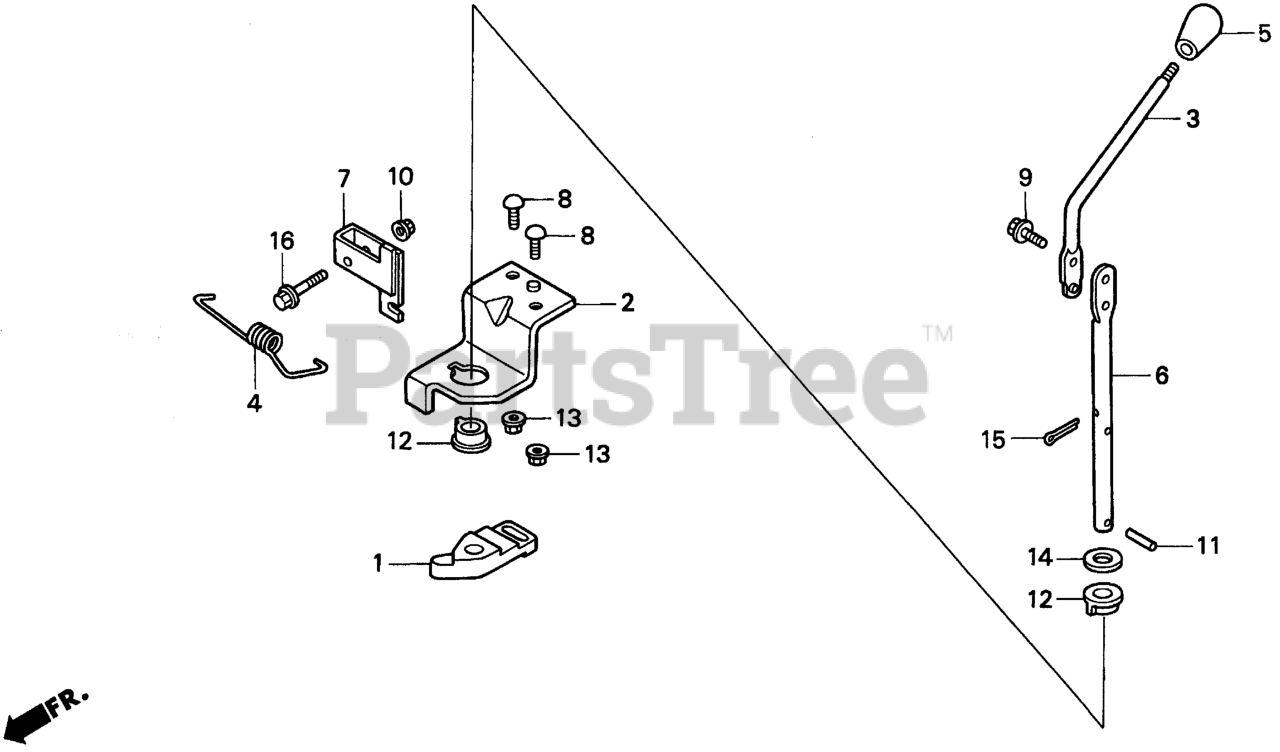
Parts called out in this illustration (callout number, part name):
1	ARM, P.T.O.
2	BASE PLATE, P.T.O. ARM
3	LEVER, P.T.O. CLUTCH
4	SPRING, P.T.O. LEVER
5	GRIP, P.T.O. LEVER
6	SHAFT, P.T.O. CLUTCH
7	PLATE, P.T.O. SWITCH
8	BOLT, SPECIAL (8X20)
9	BOLT, SPECIAL (8X16)
10	NUT, SELF-LOCK (6MM)
11	PIN, P.T.O. ARM
12	BUSH, P.T.O. SHAFT
13	NUT, FLANGE (8MM)
14	WASHER, PLAIN (16MM)
15	PIN, COTTER (4.0MM)
16	BOLT, FLANGE (6X32)
